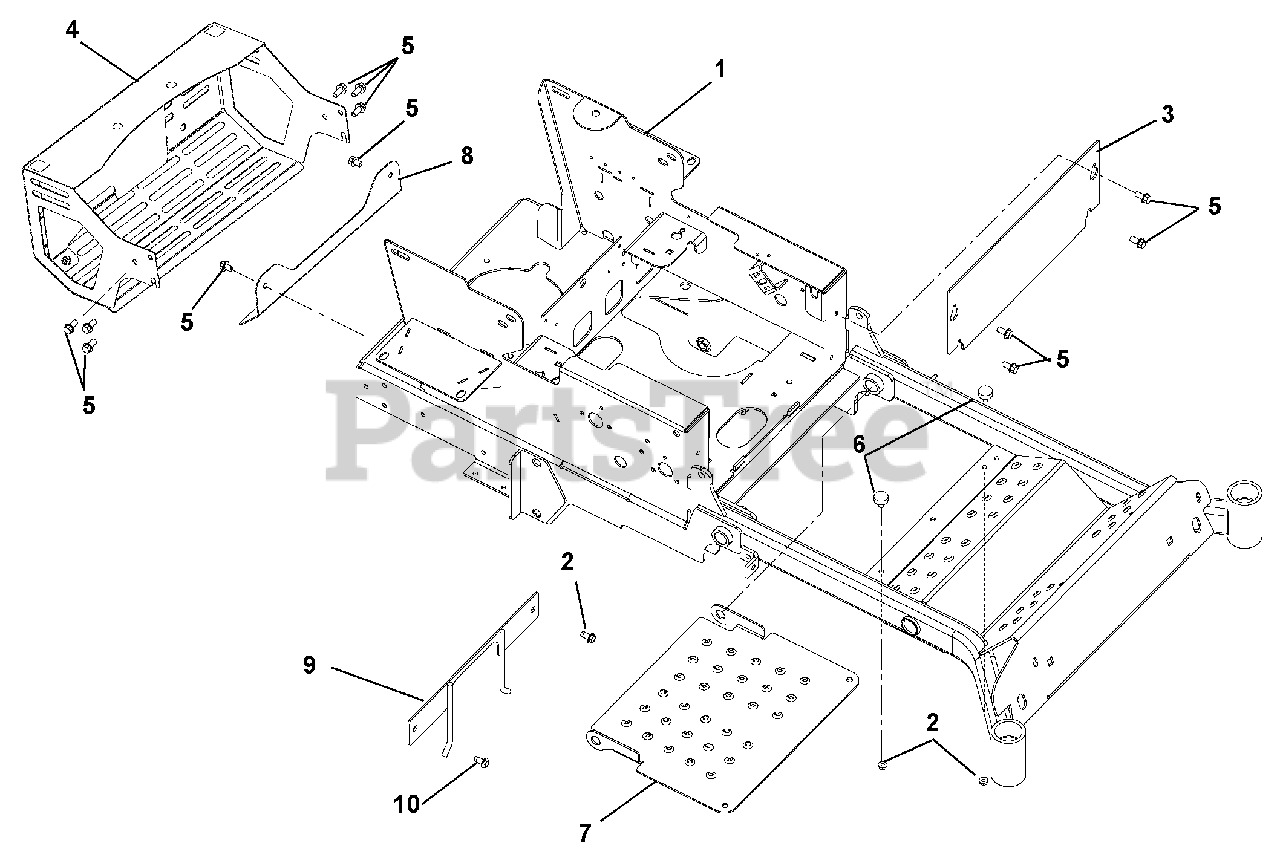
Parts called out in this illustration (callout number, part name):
1	WLDMT, 48" HD FRAME
2	@NUT-SPNLK-FLG .312-18 YWZC
3	PLATE, KICK
4	KIT, BUMPER ARIENS MAX ZOOM
5	@SCR-TAP .38-16X.75 HWH TR YWZ
6	BUMPER, RUBBER
7	PANEL, INSPECTION
8	BRKT, HEAT SHIELD - MUFFLER
9	PTO BELT FINGER WLDMT - BLK
10	@SCR-TAP .38-16X.75 HWH TR YWZ
